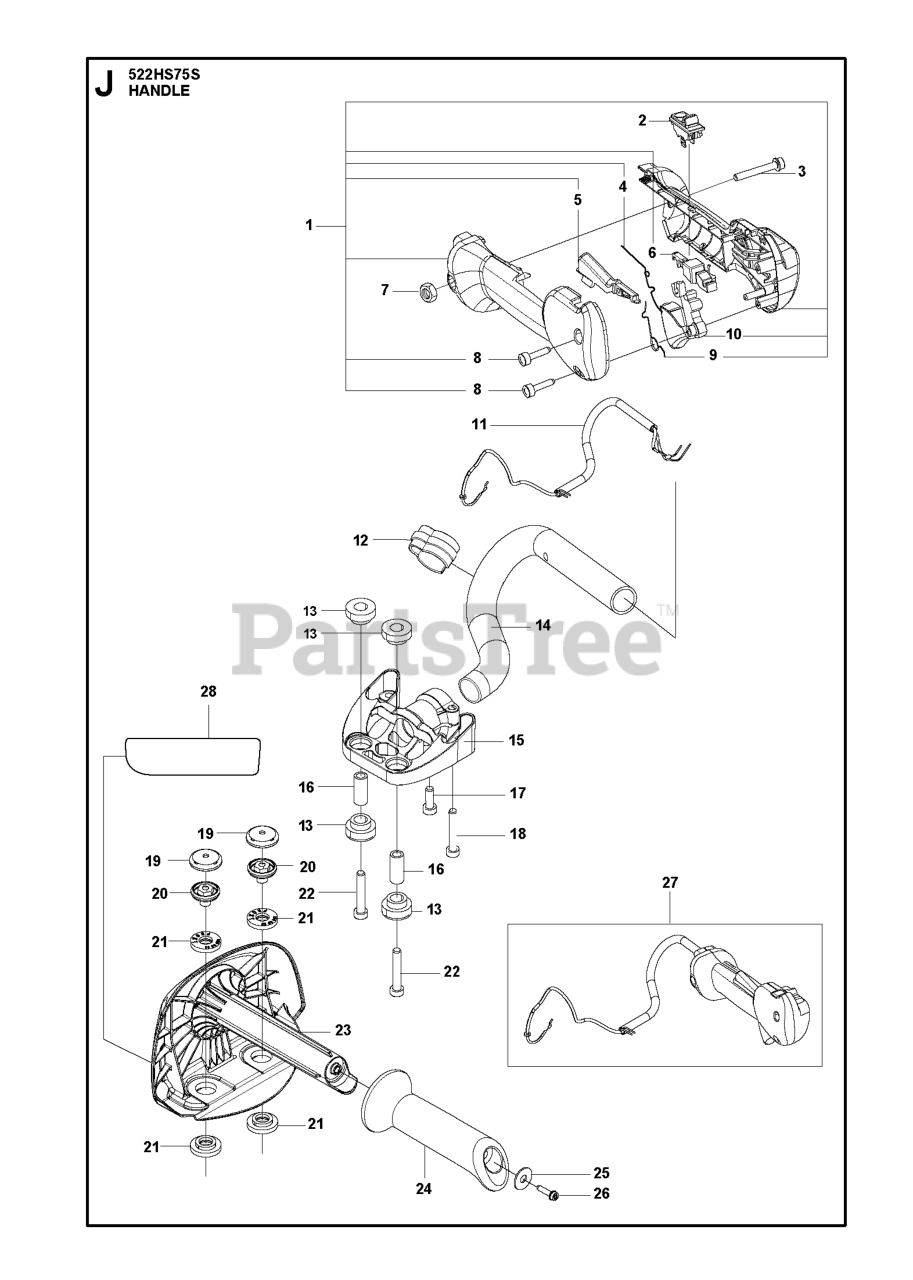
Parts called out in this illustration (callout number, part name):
1	THROTTLE HANDLE ASSY HVA, SPA
2	STOP BUTTON
3	SCREW IHSCFM
5	THROTTLE LOCKOUT
6	BUTTON BLIND BUTTON
8	SCREW IHSCT MT4X18 10.9 ZN/FE
10	THROTTLE CONTROL
11	WIRE ASSY HEDGE TRIMMER HS SCA
17	BOLT M5X8 T27 10.9
21	ANTIVIBRATION ELEMENT
23	FRONT HANDLE HS HUSQVARNA-GREY
24	HANDLE GRIP FRONT BLACK
25	WASHER 5.3X15
27	THROTTLE HANDLE ASSY
